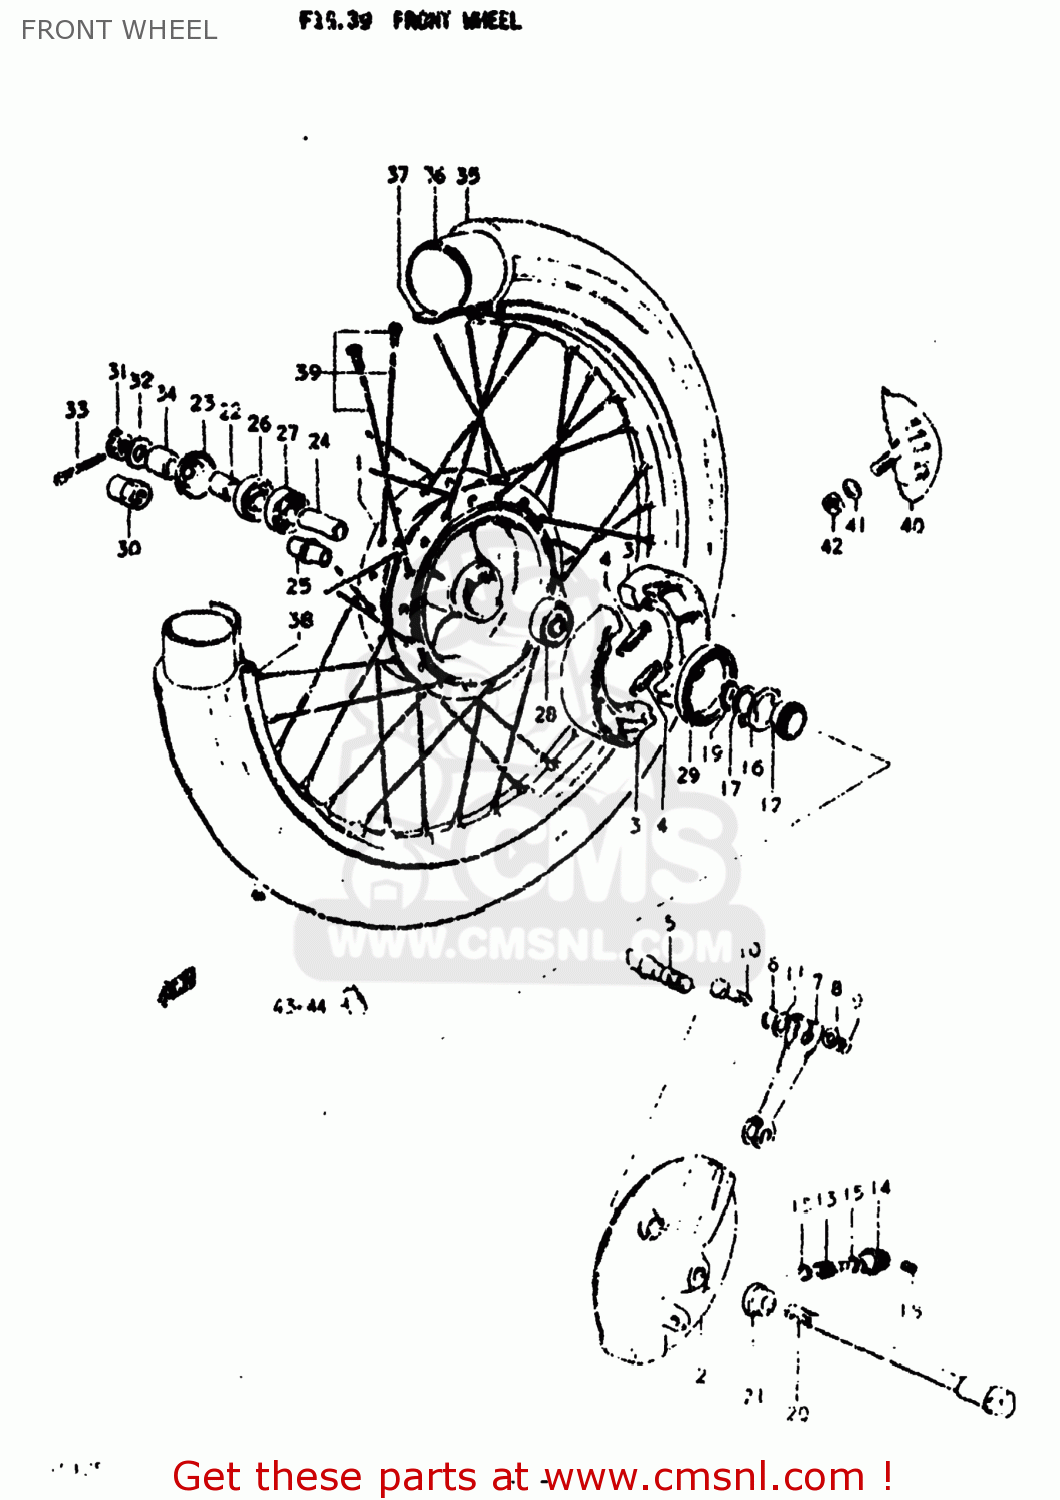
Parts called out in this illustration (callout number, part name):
1	HUB,FRONT
2	PANEL,FRONT HUB
3	SHOE,BRAKE
4	SPRING(L:34)
5	CAM,FRONT BRAKE
6	O RING(D:2.5,ID:11.4)
7	LEVER,FR BRAKE CAM
8	WASHER
9	NUT
10	BOLT
11	WASHER(12.5X20X1)
12	GEAR,SPEEDOMETER
13	PINION,SPEEDOMETER
14	BUSH,METER GEAR OUTER
15	WASHER (5.1X9X0.4)
16	DRIVER,SPEEDOMETER GEAR
17	WASHER (10.5X30X3.2)
18	SCREW
19	CIRCLIP
20	AXLE,FRONT
21	SPACER (12X20X41)
22	SPACER (12X20X44)
23	DUST SEAL,FRONT HUB DRUM
24	SPACER (12.6X19X52)
25	SPACER,FRONT HUB BEARING
26	OIL SEAL
27	BEARING
28	BEARING
29	OIL SEAL (43X58X7)
31	NUT 12MM
32	WASHER
33	COTTER PIN
34	SPACER(12X18X16.4)
35	TIRE,FRONT
36	TUBE
37	PROTECTOR,WHEEL,INNER
38	RIM,FRONT WHEEL
39	SPOKE SET,FRONT
40	STOPPER,BEAD
41	WASHER
42	NUT
43	BALANCER,WHEEL (30G)
44	BALANCER,WHEEL (50G)
